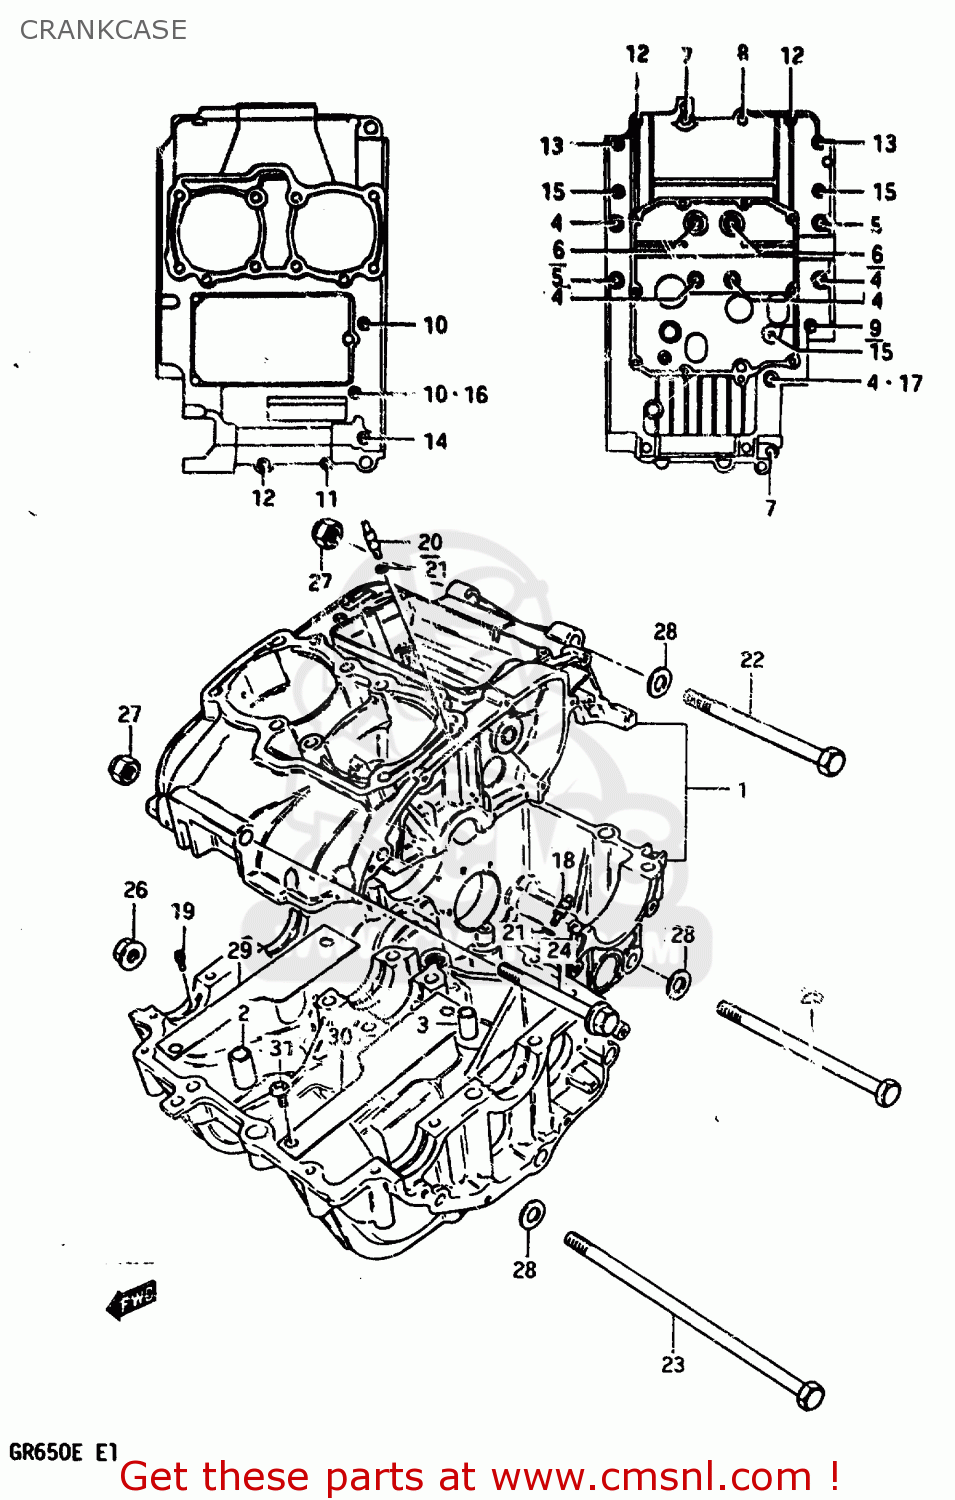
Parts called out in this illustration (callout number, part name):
1	CRANKCASE SET
2	PIN(10.4X13X22)
3	PIN (11X20)(SUS)
4	BOLT
5	BOLT
6	BOLT
7	BOLT (8X50)
8	BOLT 8X60
9	BOLT(6X100)
10	BOLT
11	BOLT (6X40)
12	BOLT 6X50
13	BOLT ,6X60
14	BOLT
15	BOLT (6X90)
16	GASKET(6.2X13X1.2) (NAS)
17	GASKET 8.2X14X1 (NAS)
18	JET,OIL GALLERY
19	JET,AIR
20	JET,AIR(14)
21	O RING(D:1.2,ID:4)
22	BOLT
23	BOLT
24	BOLT
25	BOLT 10X150
26	NUT 10MM
27	NUT
28	WASHER
29	PLATE,OIL SEPARATOR
30	PLATE,OIL SEPARATOR,LEFT
31	SCREW
